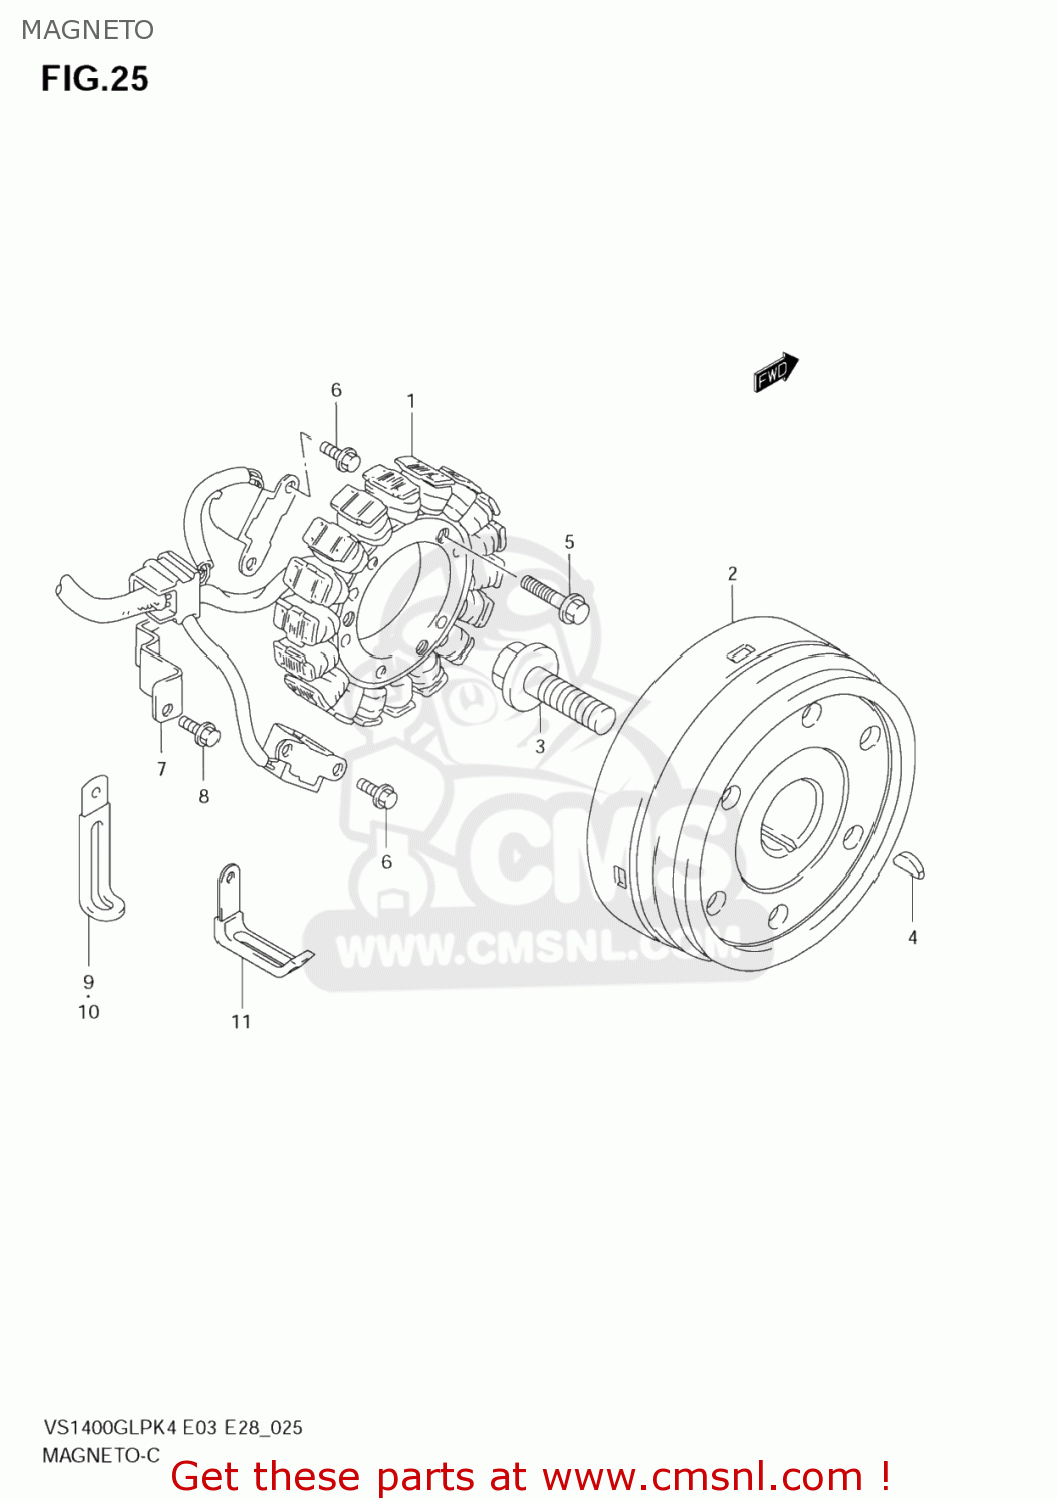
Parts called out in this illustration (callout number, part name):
1	STARTER ASSY
2	ROTOR ASSY
3	BOLT(14X43)
4	KEY
5	BOLT
6	BOLT
7	CLAMP,MAGNETO LEAD WIRE
8	BOLT
9	CLAMP(L:80)
10	CLAMP(L:45)
11	CLAMP(L:35)
